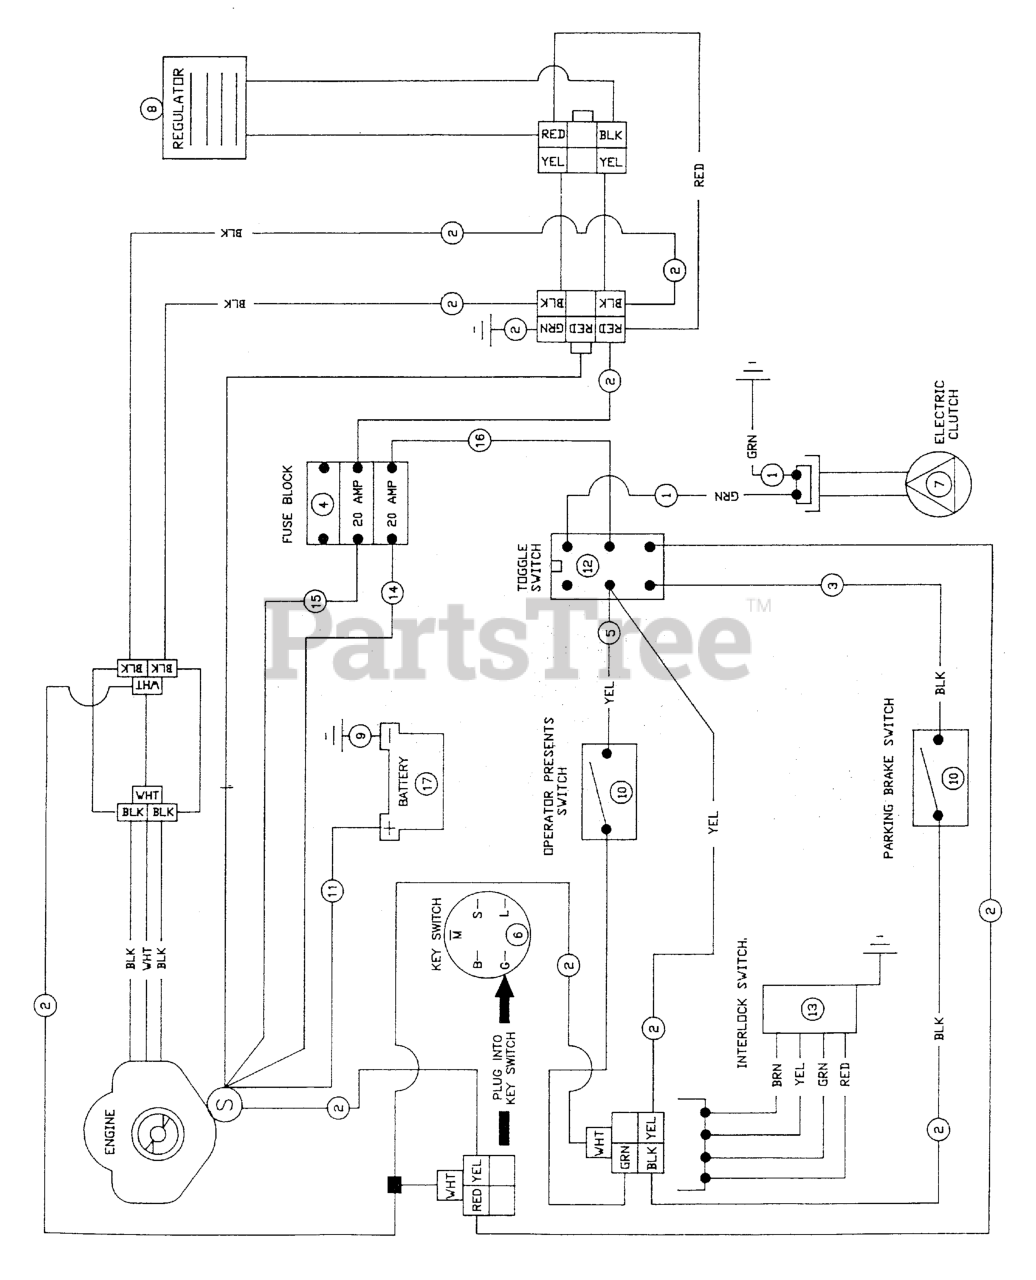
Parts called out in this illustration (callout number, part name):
1	Electric Clutch Harness
2	Main Wire Harness
3	Black Wire Assembly
4	Fuse Block
4	20 Amp Fuse
5	Yellow Wire Assembly
6	SWITCH, Ignition
7	CLUTCH, Electric, 1" Shaft
9	Negative Battery Cable
10	SWITCH, Plunger, NO
11	Positive Battery Cable
12	Toggle Switch
13	Saftey Interlock
14	Red Wire Assembly
15	Red Wire Assembly
16	Red Wire Assembly
17	BATTERY, Lawn & Garden, 12V (BCIU1, 340 CCA)
